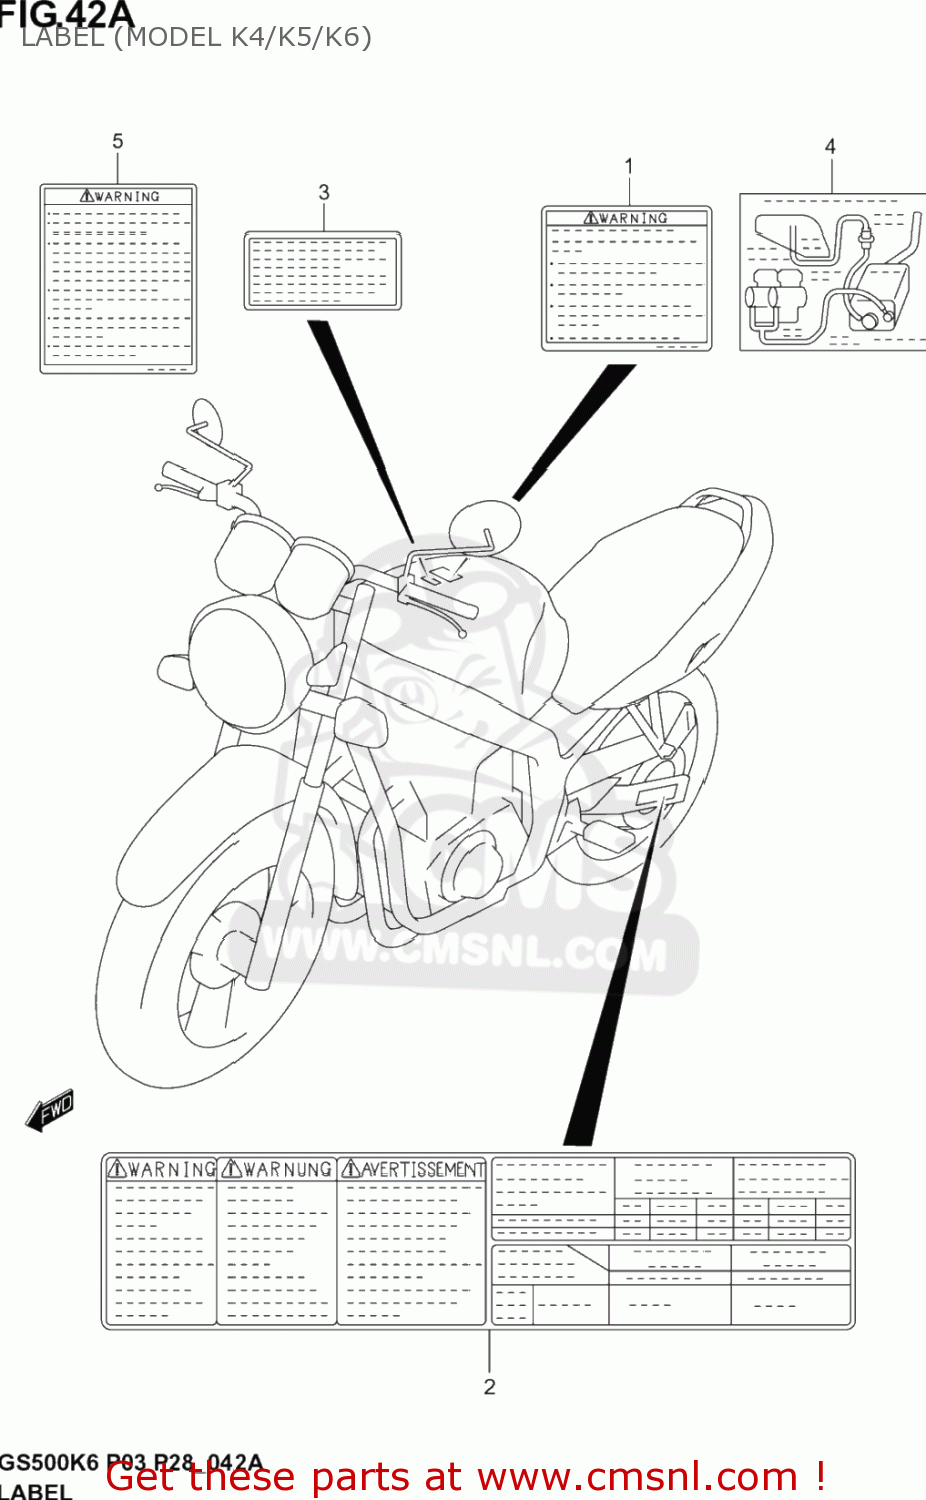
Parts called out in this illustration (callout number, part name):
1	LABEL,GENERAL WARNING
2	LABEL, TIRE
3	LABEL,MANUAL NOTICE
4	LABEL,VACUUM HOSE ROUTING
5	LABEL,SCREEN
6	MANUAL, OWNER'S (ENGLISH)
